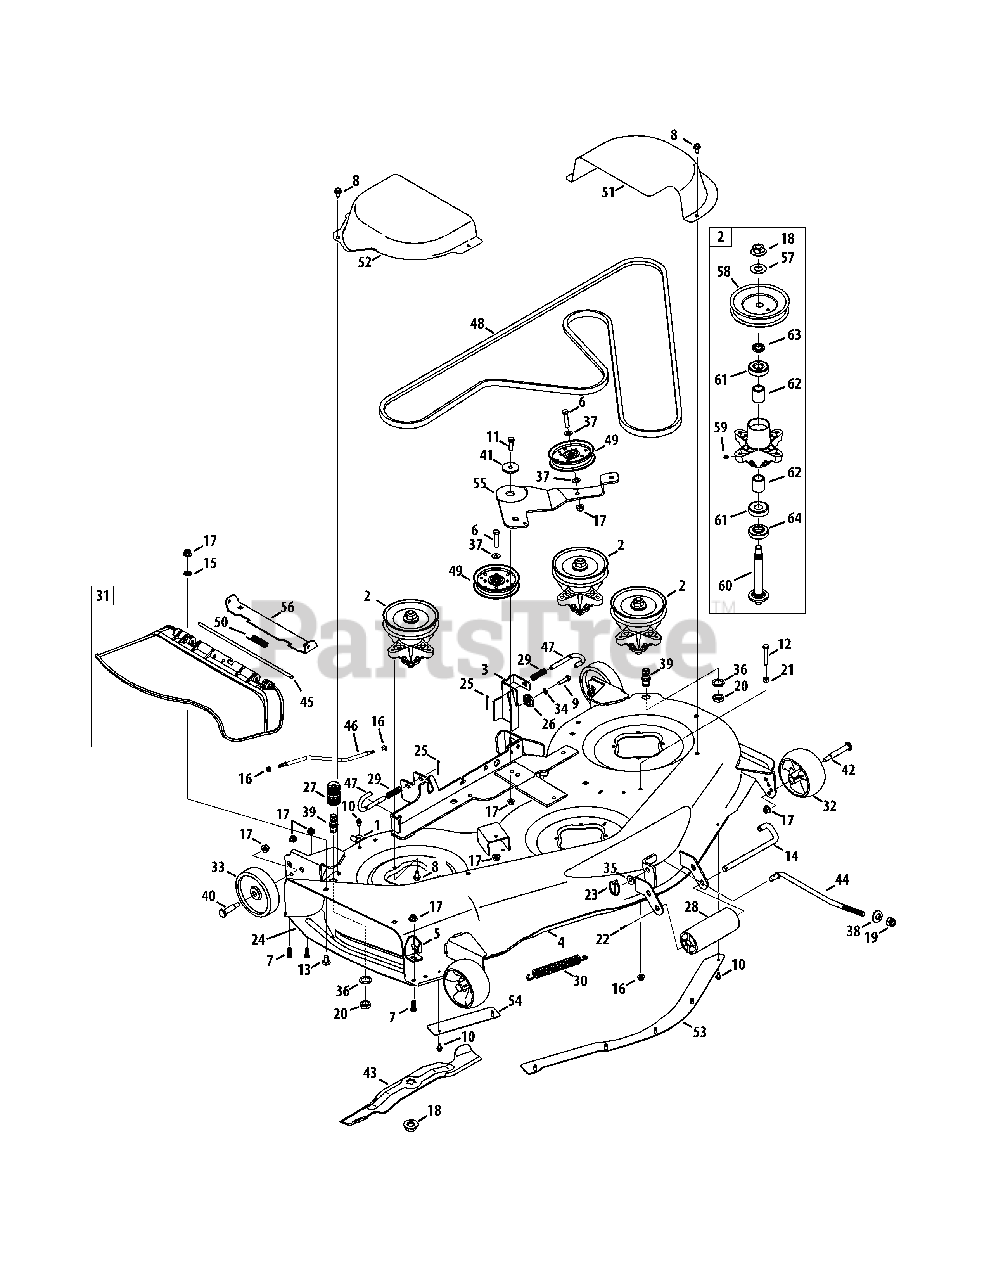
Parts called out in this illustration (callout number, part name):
1	Bracket, Hook, Retainer
2	Spindle Assembly, Pulley, 5.39 Dia.
3	Bracket Assembly, Deck, Hanger LH
4	Deck Assembly, 50"
5	Stop, Chute, Deflector
6	Hex Screw, 3/8-16, 1.75, Gr5
7	Hex Screw, 3/8-16, 1.00, Gr5, Spec
8	Screw, Self-tapping, 5/16-18, .750,
9	Hex Screw, 5/16-18, 1.25, Gr5, Std
10	Screw, Self-tapping, 1/4-20, 0.500
11	Hex Screw, 3/8-16, 1.25
12	Hex Screw, 5/16-18, 2.00, Gr5, Std
13	Bolt, Carriage, 3/8-16, 0.75, Gr1
14	Roller Pin-1/2 Dia. x 7.31
15	Nut, Push, 3/8
16	Nut, Flange Lock, 5/16-18, Nylon
17	Nut, Flange Lock, 3/8-16, Nylon
18	Nut, Flange, 5/8-18
19	Nut, 1/2-13
20	Nut, Hex, M16-1.5
21	Nut, Hex, 5/16-18, Gr5
22	Pin, Cotter, 3/32, 1.0
23	Pin, Lynch, .1875
24	Finger Guard
25	Pin, Cotter, 1/8 x 1.25
26	Gear, Deck, Adjustment
27	Coupler, Water
28	Roller, Front
29	Spring, Compr’, .53 OD x 1.75
30	Spring, Extension, .94 OD x 6.74
31	Chute Assembly
32	Wheel, Deck, 5.0 Dia. Ball
33	Wheel, Deck 5.0 x 1.38
34	Washer, Lock, 5/16, Regular Duty
35	Washer, Flat, .531 x 1.25 x .100
36	Washer, Lock, 5/8, Int Tooth
37	Washer, Flat, .406 x .875 x .059
38	Washer, Bell, .63 x 1.25 x .18
39	Port, Water
40	Bolt, Shoulder, .496 x 1.525, 3/8-16
41	Spacer, Shoulder, .8840 x .190
42	Bolt, Shoulder, .496 x 2.50, 3/8-16
43	Blade, 17.90 Star 2 In 1
44	Rod, Lift, Deck, Front, 11.7
45	Pin, Hinge, .3175 Dia. x 14.06 ,1
47	Rod, Deck Release
48	Belt, V-Type
49	Pulley, Idler, 4.25"Dia.
50	Spring, Torsion, .44 I.D. x 2.0,
51	Cover, Belt, LH 50"
52	Cover, Belt, RH 50"
53	Skirt, Center, 50"
54	Skirt, RH, 50"
55	Bracket, Idler, 50" w/o Spacer
56	Bracket, Chute 50/54"
57	Washer, Flat, .760 X 1.50 X .120
58	Pulley, Deck, 5.39 Dia.
59	Lube Fitting, 3/16
60	Shaft, Spindle, 5.75 Lg.
61	Bearing, Ball, .787id x 1.85 Od x .551
62	Spacer, .80 x 1.10 x 1.322
63	Spacer, .790 x 1.25 x .175
64	Spacer, .79 x 1.82 x .55lg.
